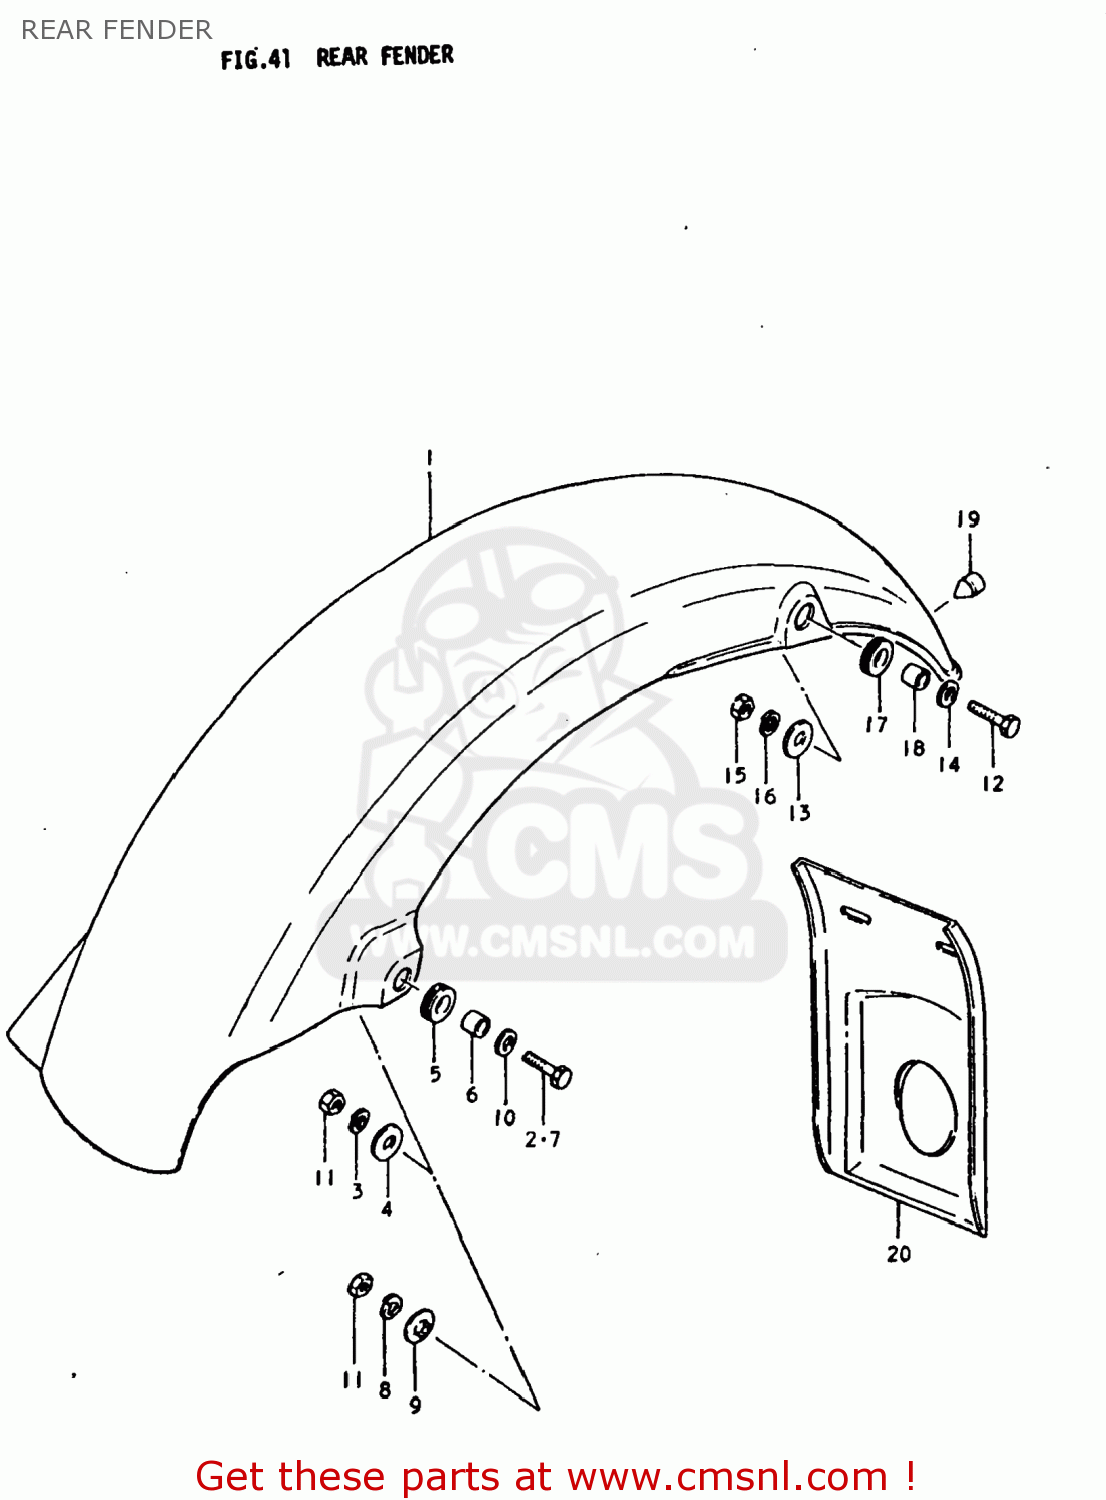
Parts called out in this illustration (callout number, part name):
1	FENDER,REAR
2	BOLT
3	LOCK WASHER
4	WASHER (6.5X20X1.2)
5	CUSHION
6	SPACER(6.1X9X7.5)
7	BOLT, UPPER
8	LOCK WASHER
9	WASHER
10	WASHER
11	NUT
12	BOLT (8X30)
13	WASHER(8.5X26X1.2)
14	WASHER
15	NUT
16	LOCK WASHER
17	CUSHION
18	SPACER (8.2X12X7.5)
19	CUSHION
20	MUD GUARD,REAR FENDER
